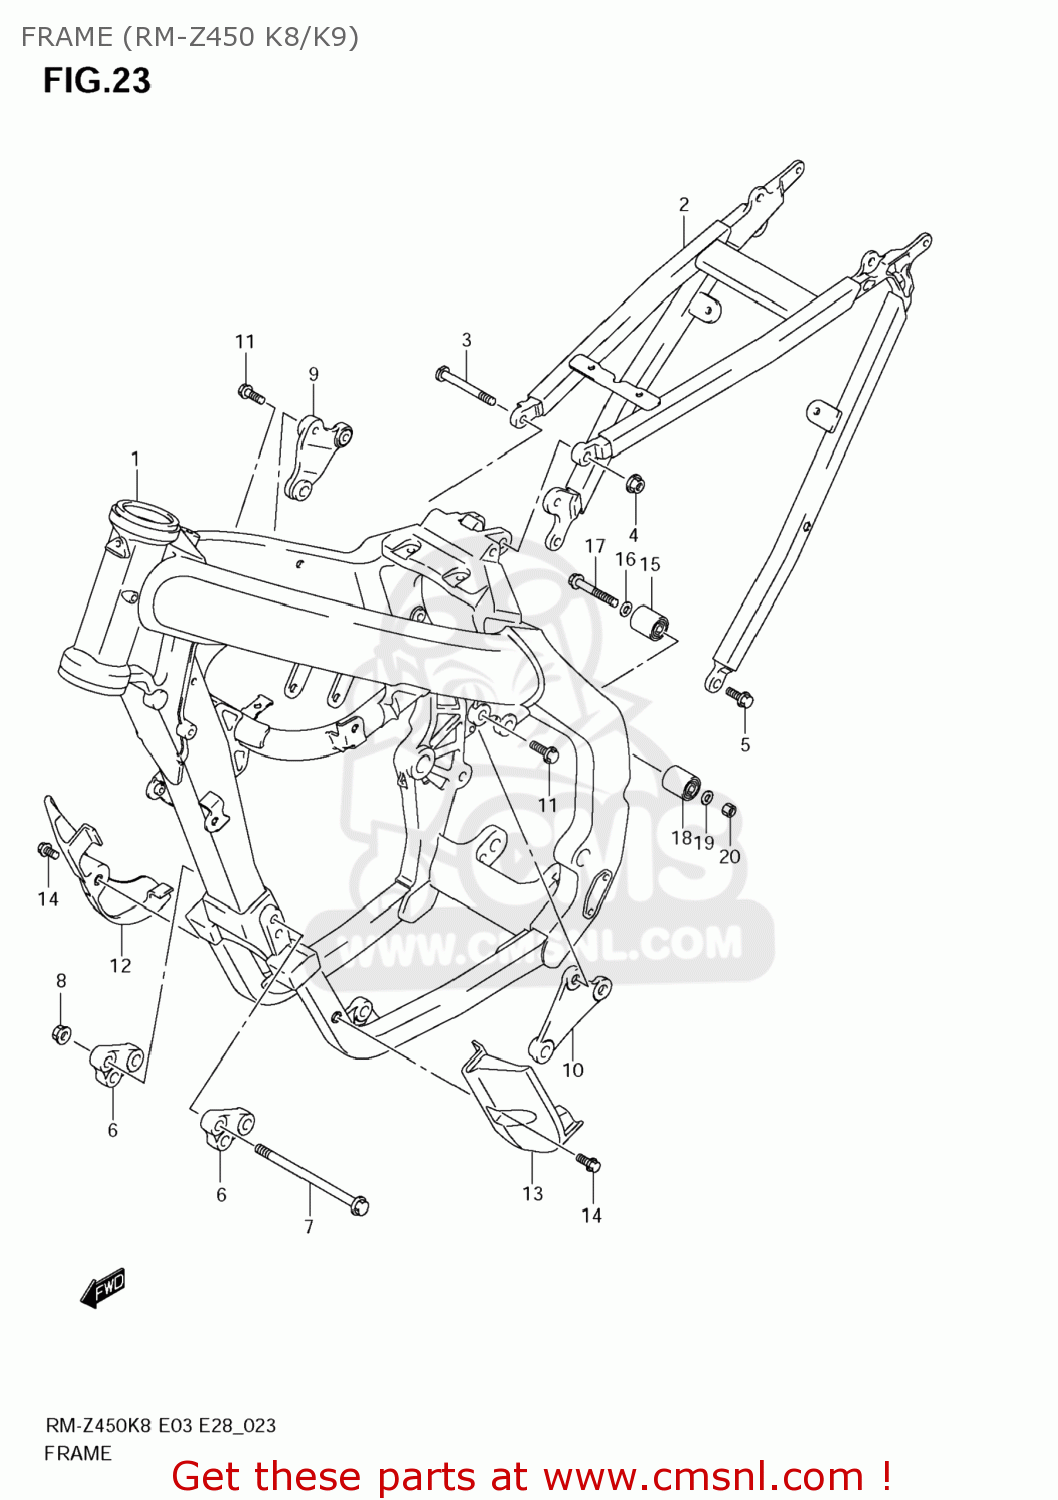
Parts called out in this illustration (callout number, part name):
1	FRAME
2	RAIL,SEAT
3	BOLT,SEAT RAIL UPR
4	NUT
5	BOLT(8X20)
6	BRACKET,ENGINE MOUNTING FR
7	BOLT(10X135)
8	NUT
9	BRACKET,ENGINE MOUNTING UPR,R
10	STEUN
11	BOLT(8X21)
12	PROTECTOR,FR,R
13	PROTECTOR,FR,L
14	BOLT(6X25)
15	ROLLER,CHAIN
16	SHIM(8X16X1)
17	BOLT(8X45)
18	ROLLER,CHAIN
19	SHIM(8X12X1)
20	NUT
